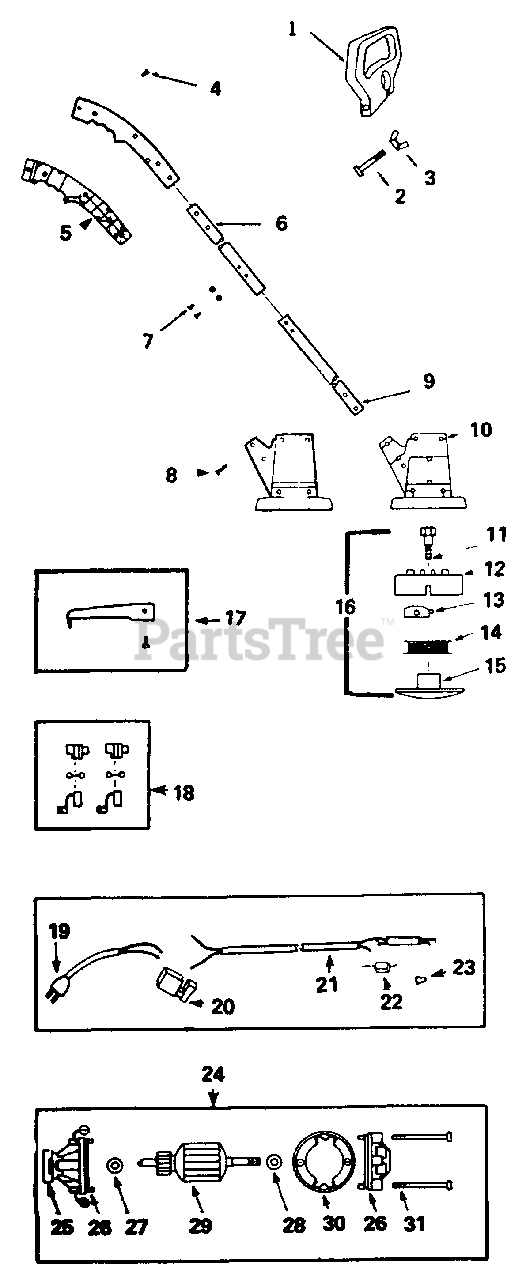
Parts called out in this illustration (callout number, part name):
1	ASSIST HANDLE
3	WING NUT
4	SCREW
5	TRIGGER HANDLE SET
6	TUBE, UPPER
7	TUBE FASTENER KIT
8	SCREW
9	TUBE, LOWER
10	MOTOR HOUSING SET
11	ADAPTOR
12	HUB w/LINE SAVERS
13	LINE SAVER
14	SPOOL WOUND
15	BALL LOCK
16	HEAD ASSEMBLY
17	LINE LIMITER KIT
18	BRUSH KIT
19	POWER CORD PIGTAIL
20	SWITCH
21	HARNESS w/DIODE
22	DIODE
23	CONNECTOR
24	MOTOR
25	INSULATOR
26	END BELL SET
27	WASHER-THRUST, .025"
28	WASHER-THRUST, .010"
29	ARMATURE
30	FIELD ASSEMBLY
31	SCREW
